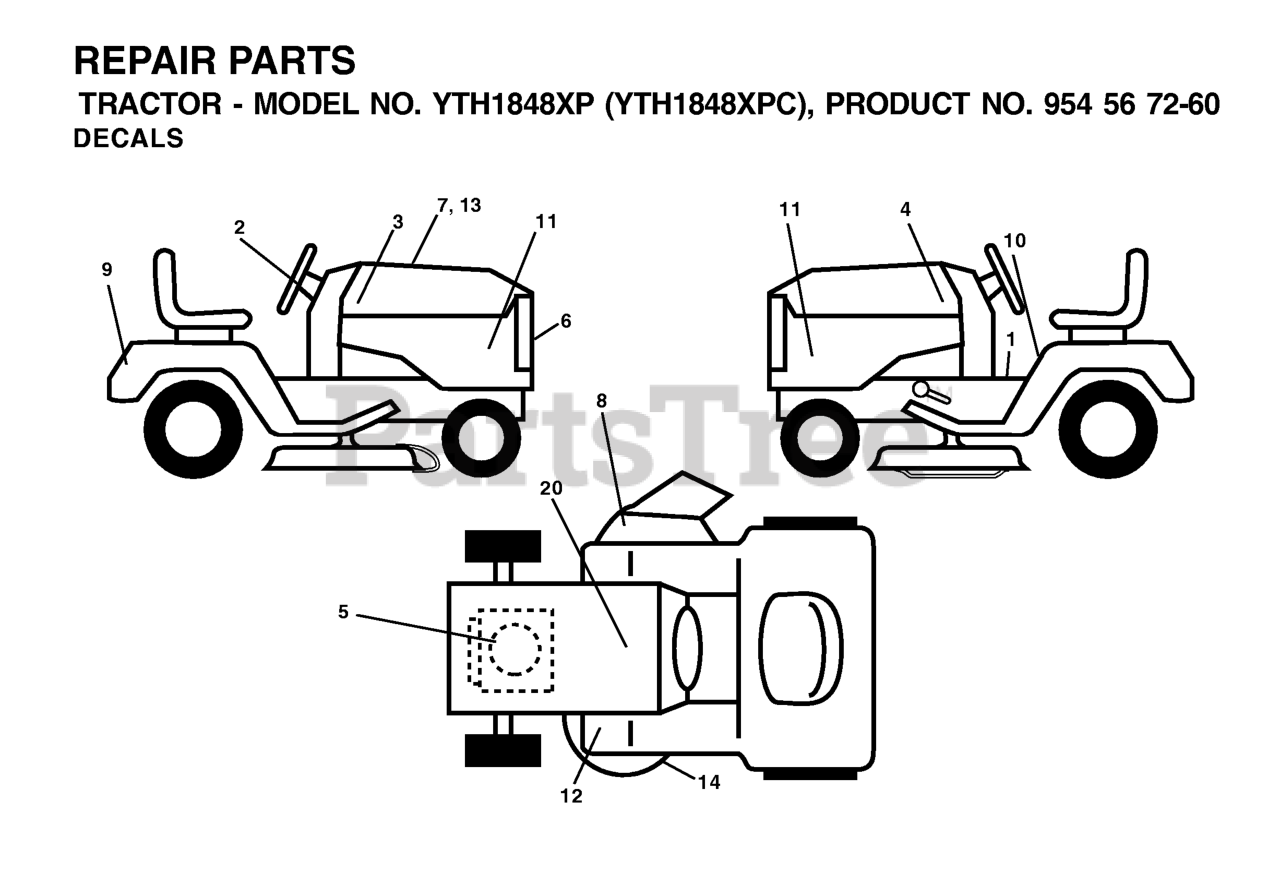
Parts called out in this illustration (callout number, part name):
2	DECAL.WHEEL.STEERING.HUSQ.PERM
6	DECAL.GRILLE.HUSQ
8	DECAL.WARN.KEEP.HAND.AWAY
9	DECAL, FENDER
10	DECAL FENDER DANGER
11	DECAL HOOD SIDES
12	DECAL CLUTCH/BRAKE
13	DECAL HOOD CUST. RESP.
14	DECAL V-BELT SCHEMATIC
20	DECAL BTRY SYMBOLS
